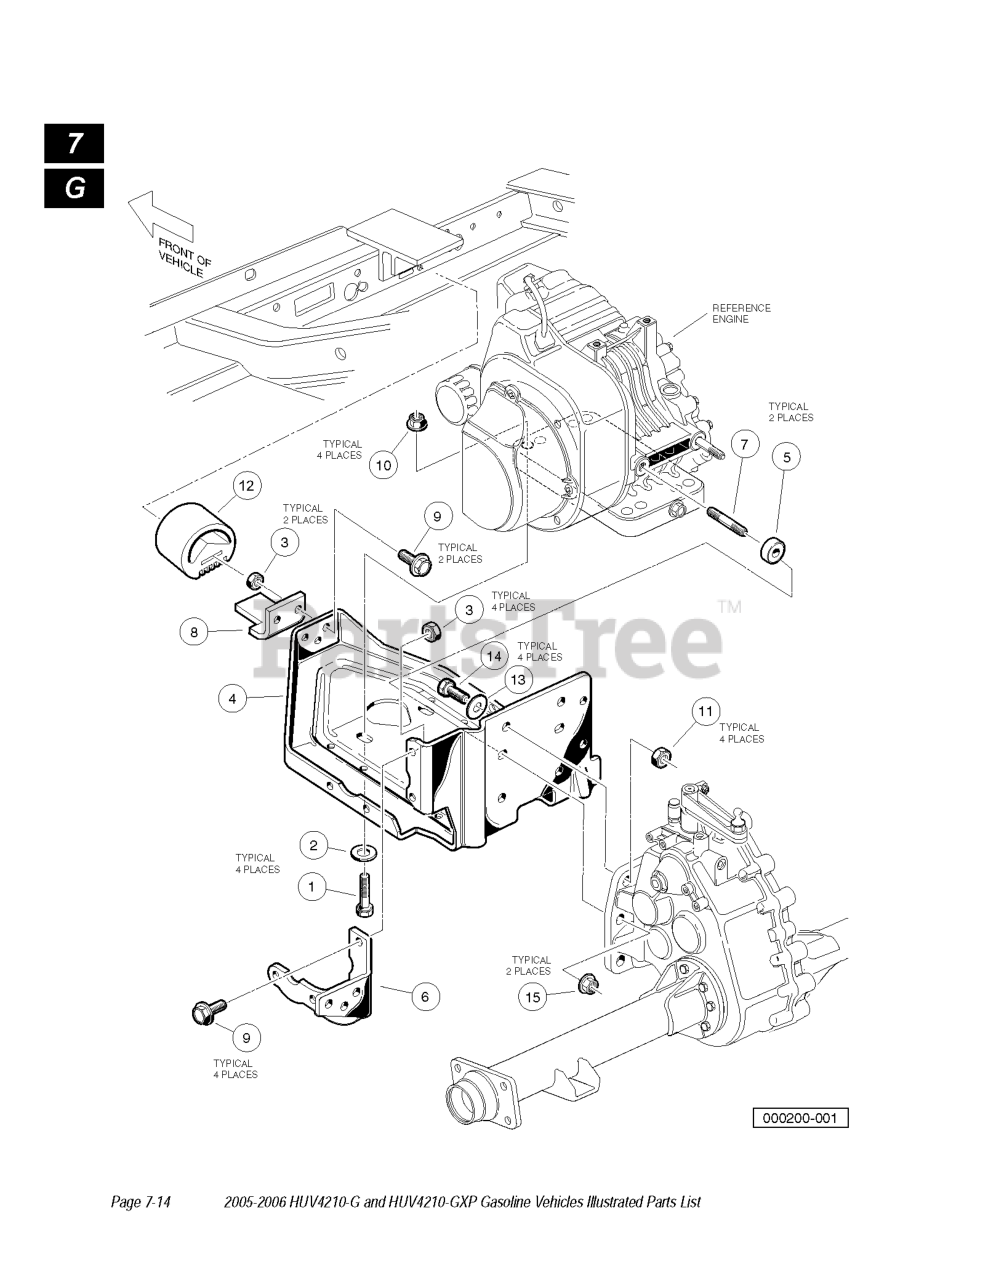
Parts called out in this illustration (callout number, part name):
1	BOLT HEX HEAD
4	PLATE, ENGINE MOUNTING
5	SPACER, POWDERED METAL
6	STIFFENER, FLYWHEEL SIDE
7	STUD, M8-1.25 X 60MM 2-ENDED
8	SNUBBER BRACKET
9	SCREW, 5/16-24 X .875 GR8 FLNG
10	LOCKNUT, 5/16-18 HEX FLANGE
11	LOCKNUT, 3/8-16 FLANGED DIMPLE
12	INNER FRAME SNUBBER
13	WASHER, 3/8 FLAT
15	NUT, M8-1.25 FLANGED HEX
